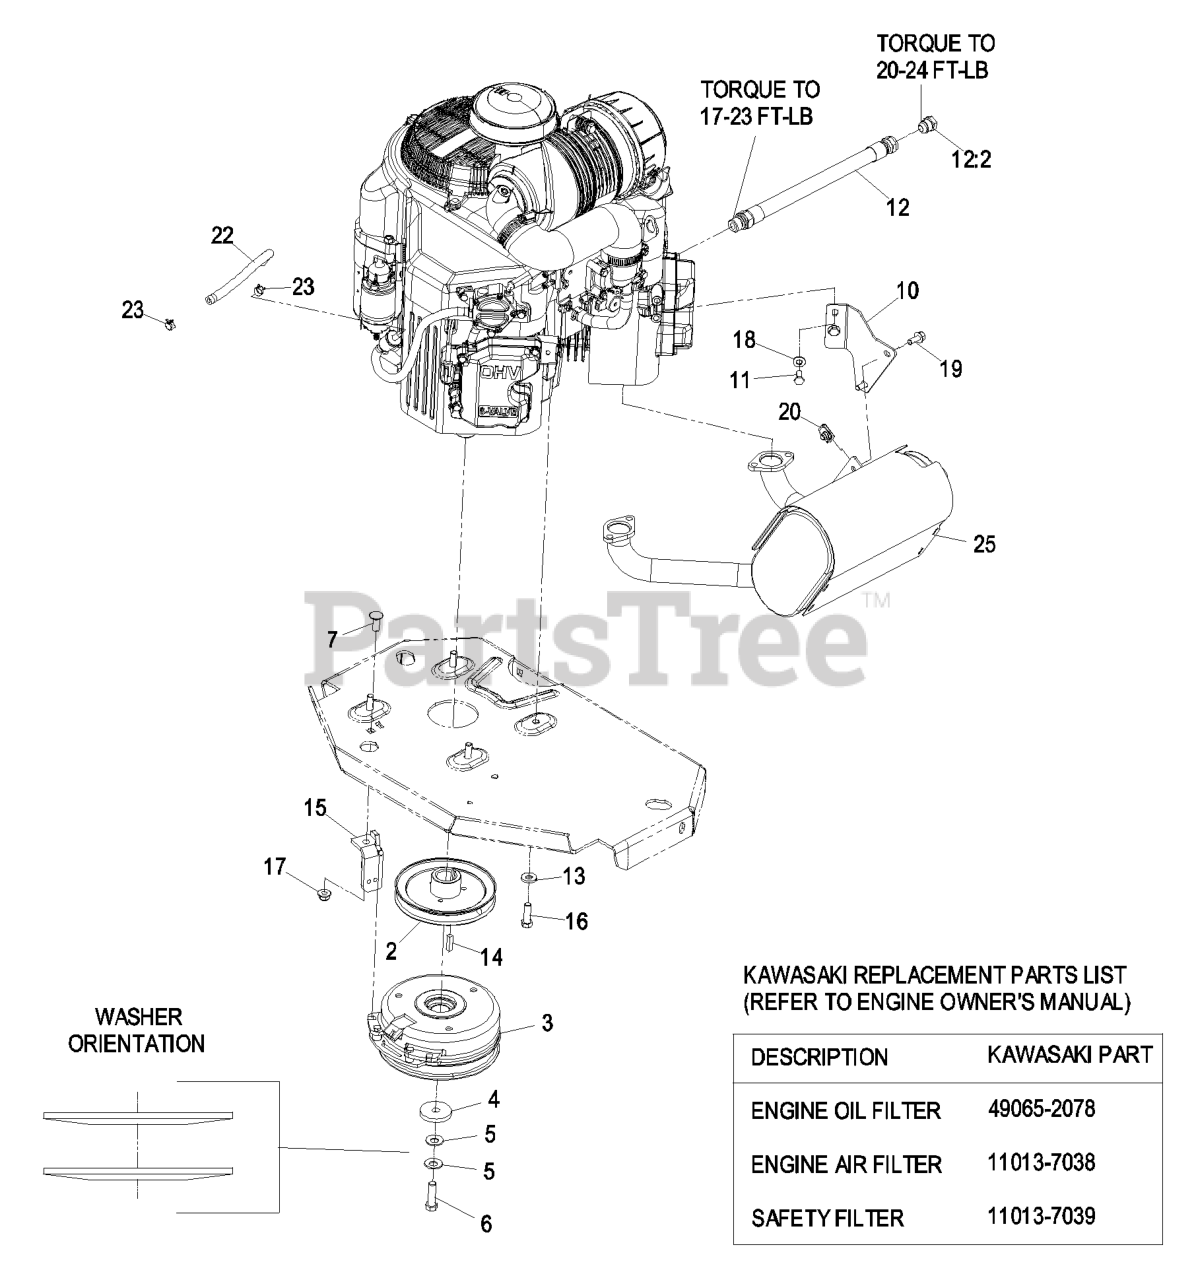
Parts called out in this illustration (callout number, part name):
2	SHEAVE
4	WASHER-CLUTCH
5	WASHER-SPRING
6	SCREW-HH 7/16-20 X 1 1/2 W/LOCTITE
7	SCREW-CARR
11	SCREW-HH
13	WASHER-BELLEVILLE
15	ANCHOR-CLUTCH
16	SCREW-HH
17	NUT-HF, NI
18	WASHER-SPRING
19	SCREW-HHF
22	HOSE-FUEL
23	CLAMP-HOSE
